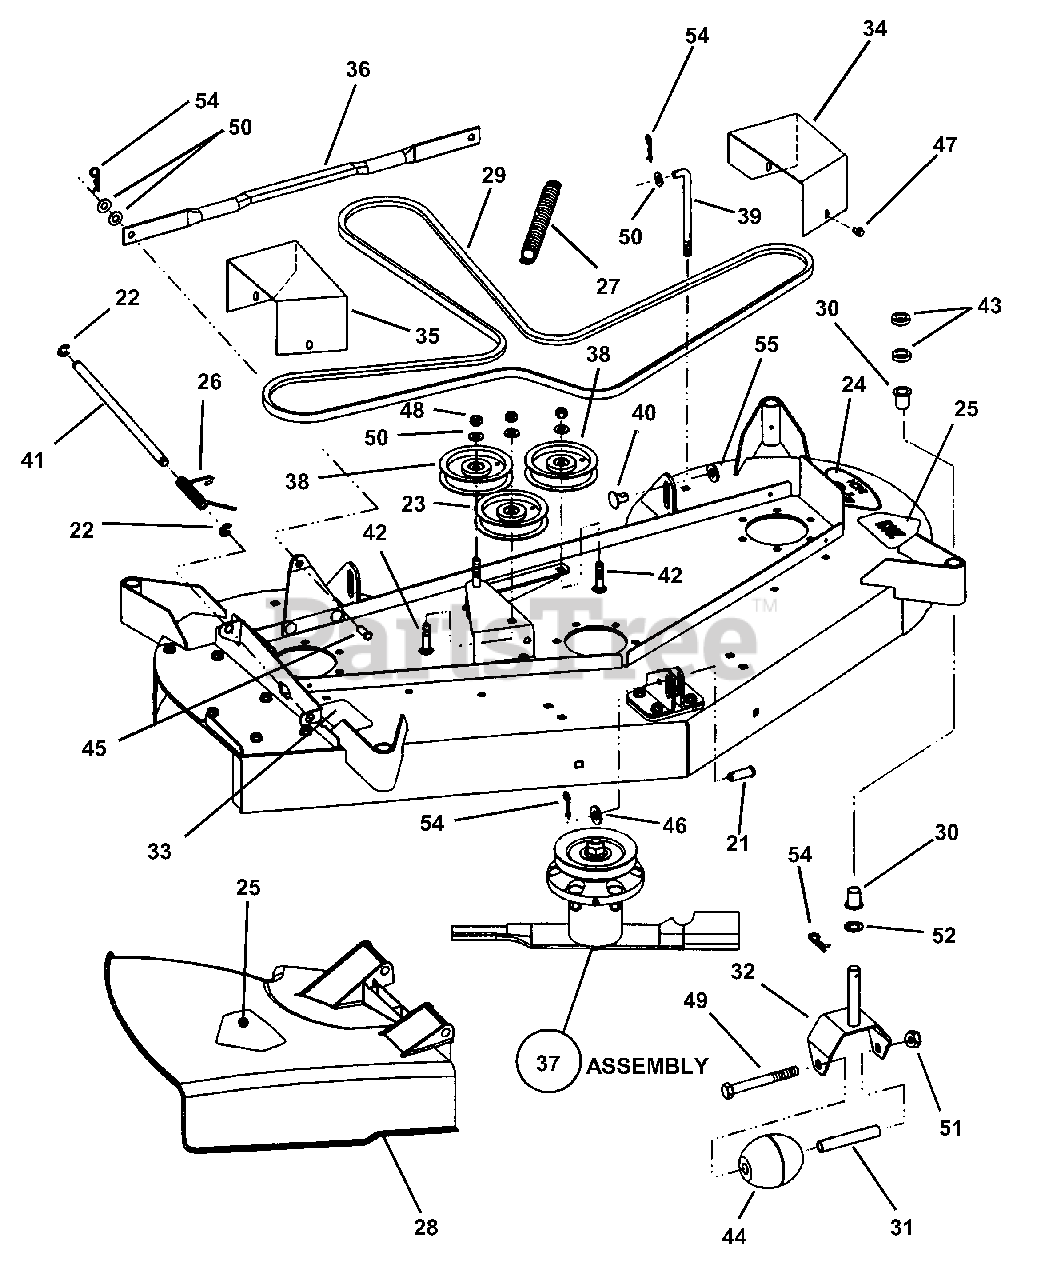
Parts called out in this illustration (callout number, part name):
21	PIN, 1/2 x 1-3/8" Clevis
22	RING, External Retaining
23	IDLER, 4.12" Flat
24	DECAL, 48" Deck
25	DECAL, CPSC
26	SPRING, Chute
27	SPRING, Idler Primary
28	CHUTE, Side Discharge
29	V-BELT, HA Section, (120.722" Nominal Effective Length)
30	BEARING, 1/2 x 3/4" Plastic
31	SLEEVE, Caster Wheel
32	WELDMENT, Bracket/Shaft Caster
33	DECAL, Chute/Deflector
34	COVER, Belt L.H.
35	COVER, Belt R.H.
36	ROD, Timing
37	ASSEMBLY, 48" Spindle
38	IDLER, 3-1/4" Flat
39	LINK, Leveling
40	SUPPORT, Swivel
41	HINGE PIN, Chute
42	BOLT, 3/8-16 x 1-3/4" Short Neck Carriage, Grade 5
43	SPACER, Blade
44	ROLLER, Low Density Polyethylene
45	PIN, 3/8 x 7/8" Clevis
46	WASHER, 1/2" Flat
47	SCREW, 1/4-20 x 3/8" Hex Washer Self-Tap
48	NUT, 3/8-16 Hex Center Lock, Grade 5 or B
49	SCREW, 1/2-20 x 4-1/2" Hex Head Cap, Grade 5
50	WASHER, 3/8" Flat
51	NUT, 1/2-20 Hex Center Lock,
52	WASHER, .64 I.D. Flat
54	HAIR PIN, 3/32 x 1-1/2"
55	WASHER, 1/2" Flat
